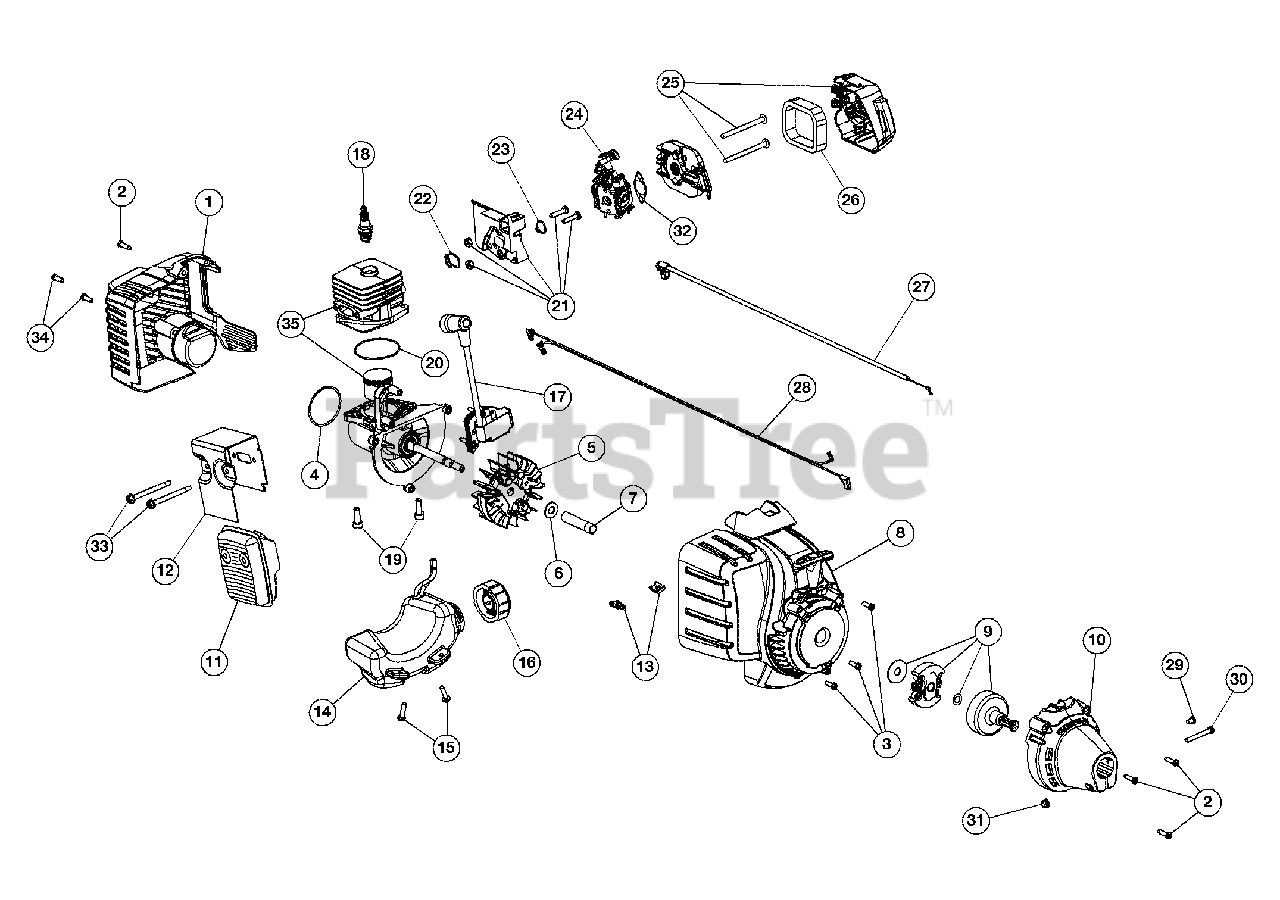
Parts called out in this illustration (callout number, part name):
1	Rear Cover Assembly (Incl. 2 & 34)
2	Cover Screw
3	Housing Screw
4	O-Ring
5	Flywheel Assembly
6	Washer
7	Spacer
8	Starter Housing (Incl. 3 & 13)
9	Clutch Assembly
10	Clutch Cover (Incl. 2)
11	Muffler Assembly (Incl. 12 & 33)
12	Muffler Gasket
13	U-shaped Nut
14	Fuel Tank Assembly (Incl. 15 & 16)
15	Tank Screw
16	Fuel Cap
17	Module Assembly
18	Spark Plug
19	Crankcase Bolt
20	Crankcase O-Ring
21	Insulator Assembly (Incl. 22 & 23)
22	Insulator O-Ring
23	Carburetor O-Ring
24	Carburetor
25	Aircleaner Cover Assembly (Incl. 26)
26	Aircleaner Filter
27	Throttle Cable
28	Lead Wires
29	Anti-rotation Screw
30	Clamp Screw
31	Clamp Nut
32	Air Cleaner Gasket
33	Muffler Screw
34	Rear Housing Screw
35	Short Block Assembly
